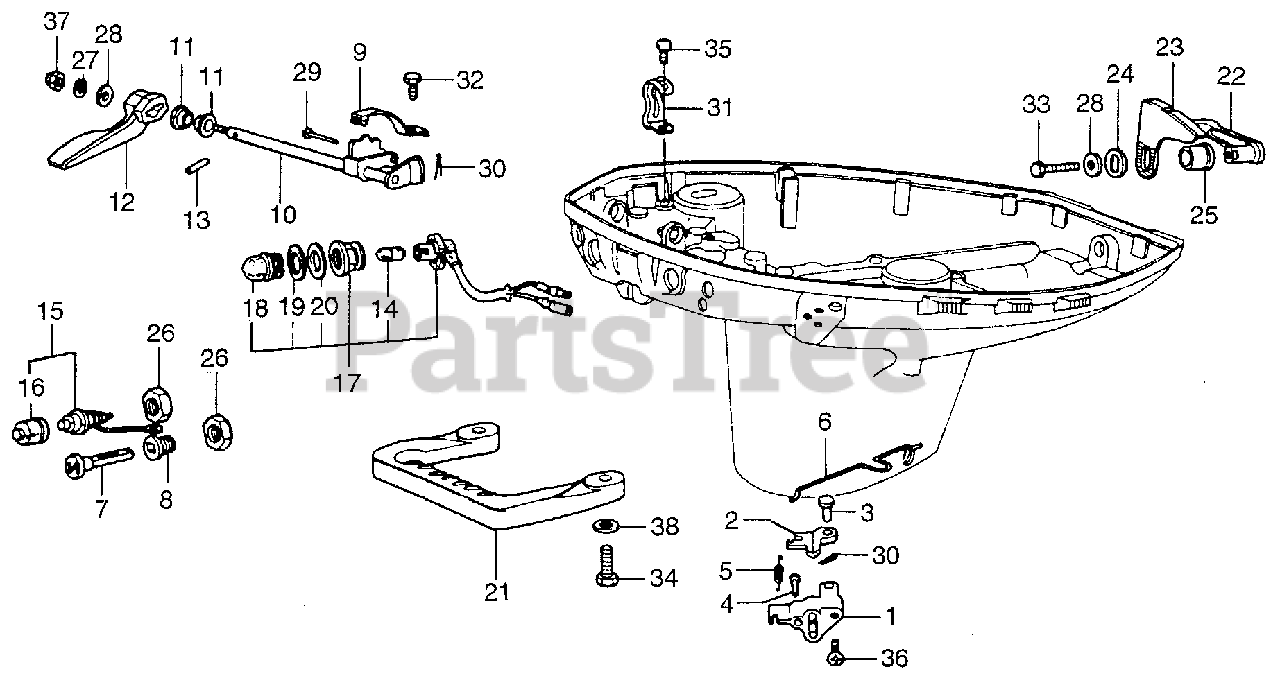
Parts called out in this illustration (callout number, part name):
1	CONNECTOR, FUEL *NH8* (DARK GRAY) (NOT AVAILABLE)
2	ARM, FUEL STOP (NOT AVAILABLE)
3	PIN (6X15) (NOT AVAILABLE)
4	SHAFT, FUEL STOP
5	SPRING, FUEL STOP (NOT AVAILABLE)
6	ROD, FUEL STOP (NOT AVAILABLE)
7	KNOB, CHOKE
8	GUIDE, CHOKE KNOB
9	SPRING, CLICK
10	SHAFT, SHIFT
11	BUSH, SHAFT
12	LEVER, GEARSHIFT *PB1* (DARK BLUE) (NOT AVAILABLE)
13	PIN, SHIFT LEVER
14	BULB, DASH (12V3.4W) (IMASEN)
15	SWITCH, ENGINE
16	CAP, BUTTON (N/A: USE P/N 36100-921-000)
17	LAMP, INDICATOR (N/A: SEE ASSEMBLY)
18	LENS (NOT AVAILABLE)
19	GASKET, LENS
20	WASHER, SPECIAL
21	HANDLE, CARRYING *PB1* (DARK BLUE)
22	LEVER, COVER LOCK *PB1* (DARK BLUE) (NOT AVAILABLE)
23	HOOK, COVER LOCK (NOT AVAILABLE)
24	WASHER, COVER LOCK
25	BUSH, COVER LOCK
26	NUT, HEX. (16MM)
27	WASHER, SPRING (6MM)
28	WASHER (6MM)
29	PIN (5X17)
30	PIN, COTTER (1.6MM)
31	CLIP, WIRE
32	BOLT, HEX. (6X12)
33	BOLT, HEX. (6X16)
34	BOLT, HEX. (8X32) (NOT AVAILABLE)
35	SCREW, PAN (5X8)
36	SCREW, FLAT (6X16)
37	NUT, CAP (6MM)
38	WASHER, PLAIN (8MM)
